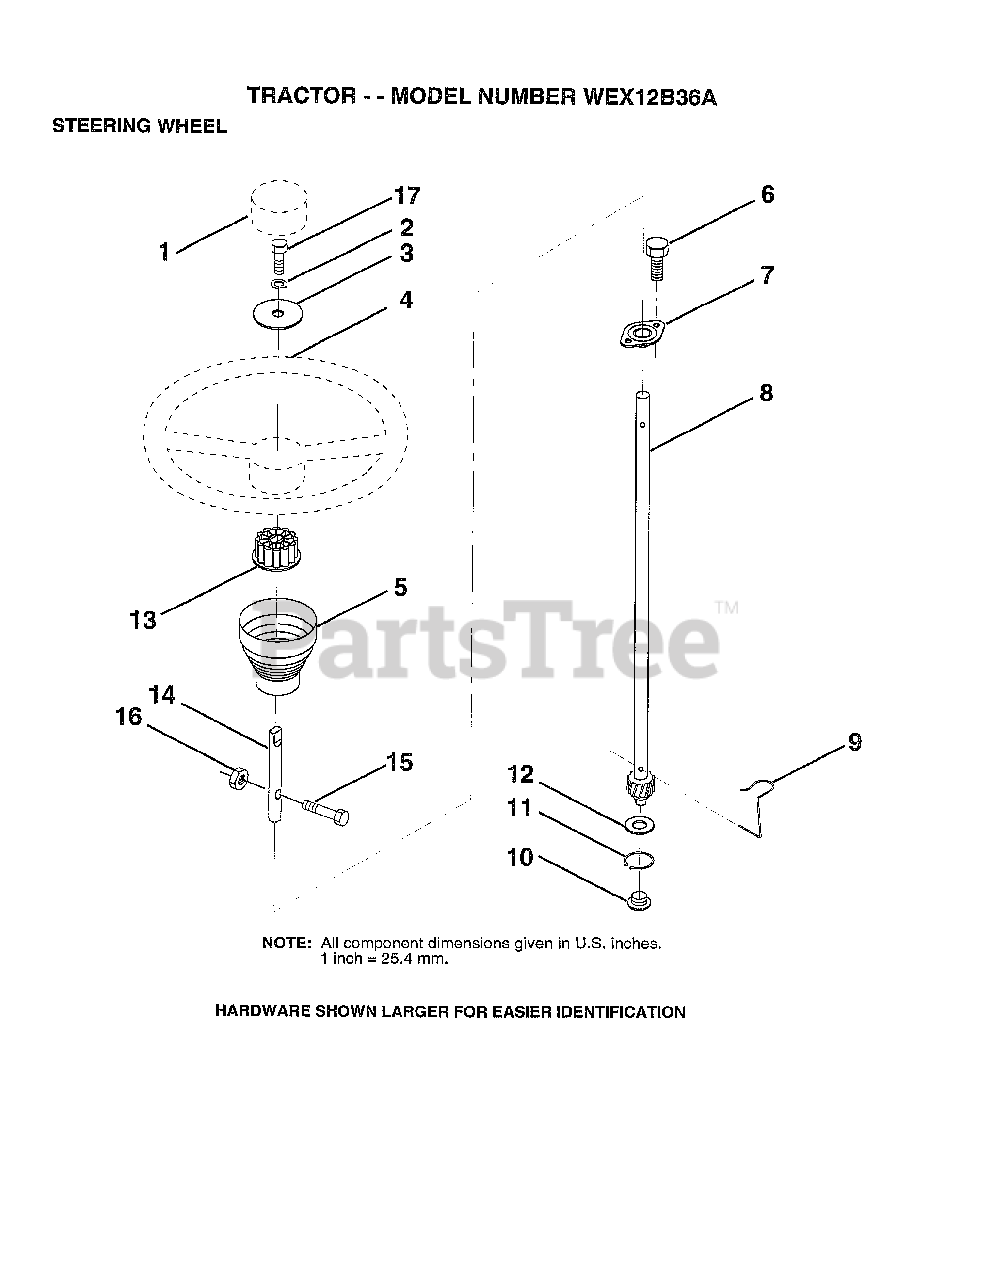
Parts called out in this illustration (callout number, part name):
1	ST WHL INSERT CAP
2	LOCKWASHER
3	WASHER T
5	SLEEVE STEERING
6	"SCREW-TT,10-32 FL"
7	BUSHING.STR.623
8	SHAFT.STEERING.LR
9	STEERING CLIP
10	BUSHING STEER LWR
11	RING
12	WASHER LT
13	ADAPTER LT
14	EXT SHAFT STEERIN
15	BOLT
16	NUT
17	BOLT
